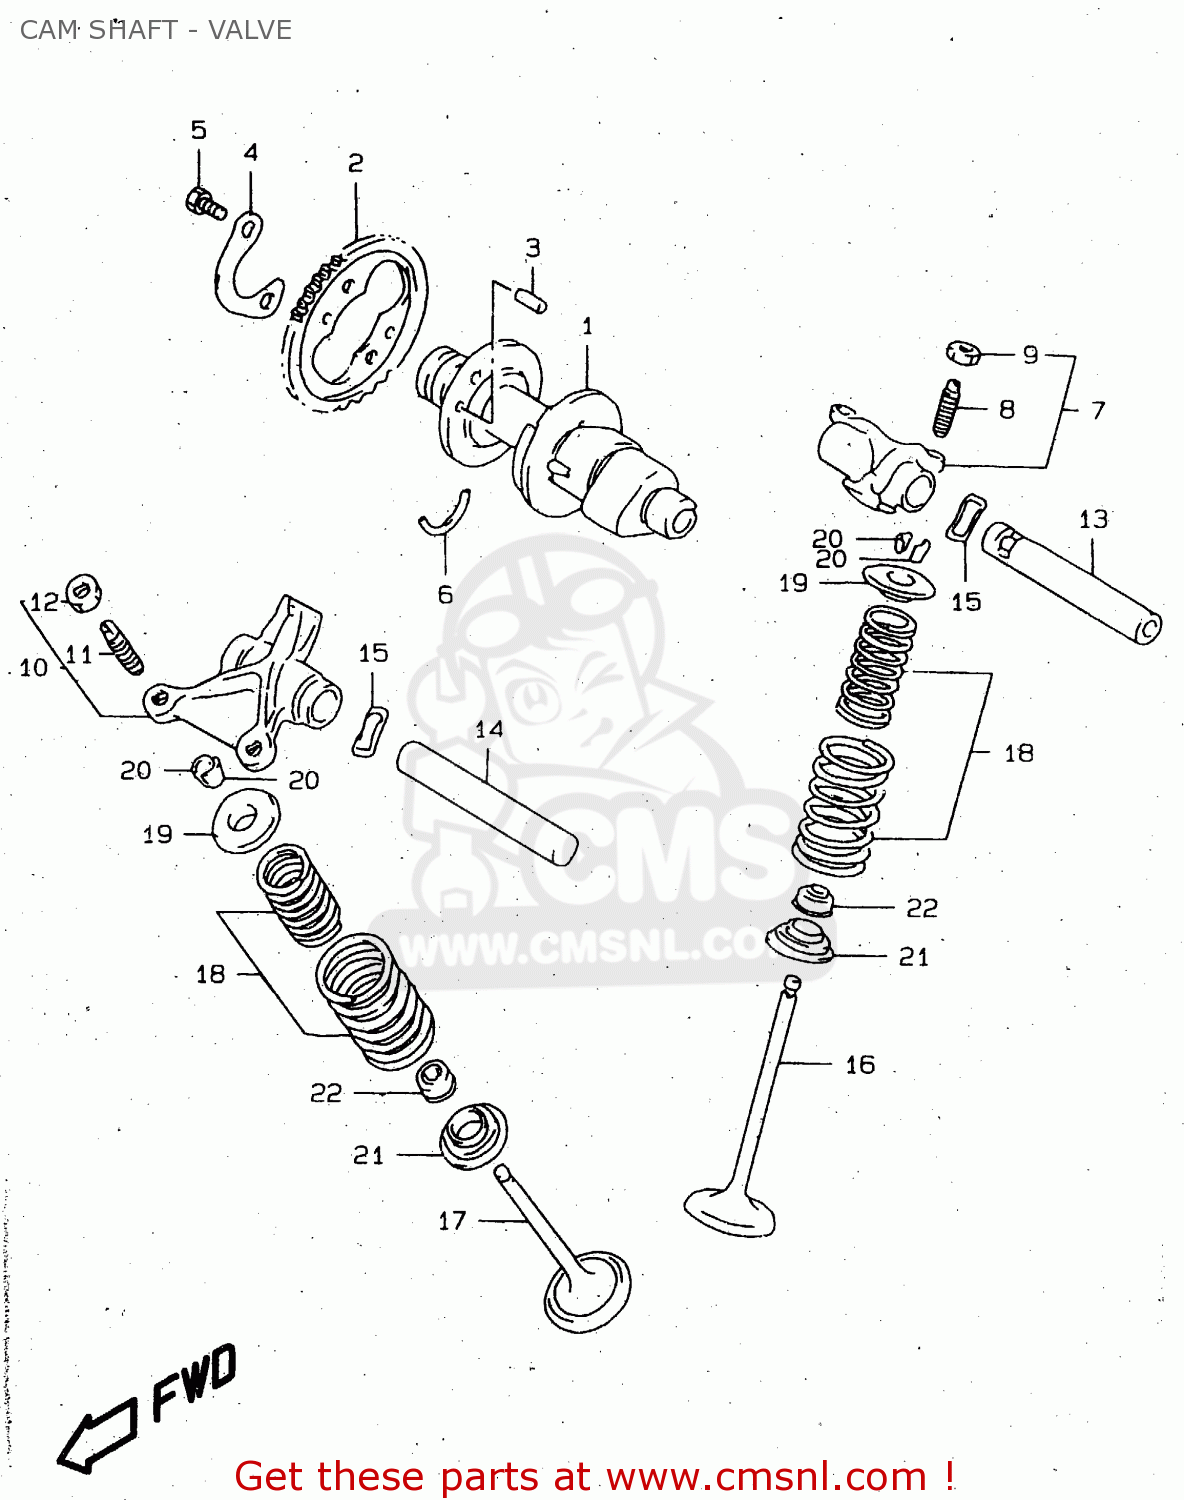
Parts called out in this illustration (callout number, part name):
1	CAMSHAFT
2	SPROCKET,CAMSHAFT(NT:38)
3	PIN(5X8)
4	WASHER,SPROCKET
5	BOLT(6X10.5)
6	C RING
7	ARM,VALVE ROCKER INTAKE
8	SCREW,TAPPET ADJUSTING
9	NUT,ADJUSTING SCREW
10	ARM,VALVE ROCKER EXHAUST
11	SCREW,TAPPET ADJUSTING
12	NUT,ADJUSTING SCREW
13	SHAFT,VALVE ROCKER ARM INTAKE
14	SHAFT,VALVE ROCKER ARM EXHAUST
15	WASHER
16	VALVE,INTAKE
17	VALVE,EXHAUST
18	SPRING SET,VALVE
19	RETAINER,VALVE SPRING
20	COTTER,VALVE
21	SEAT,VALVE SPRING
22	SEAL,OIL(5.5X11X8.2)
